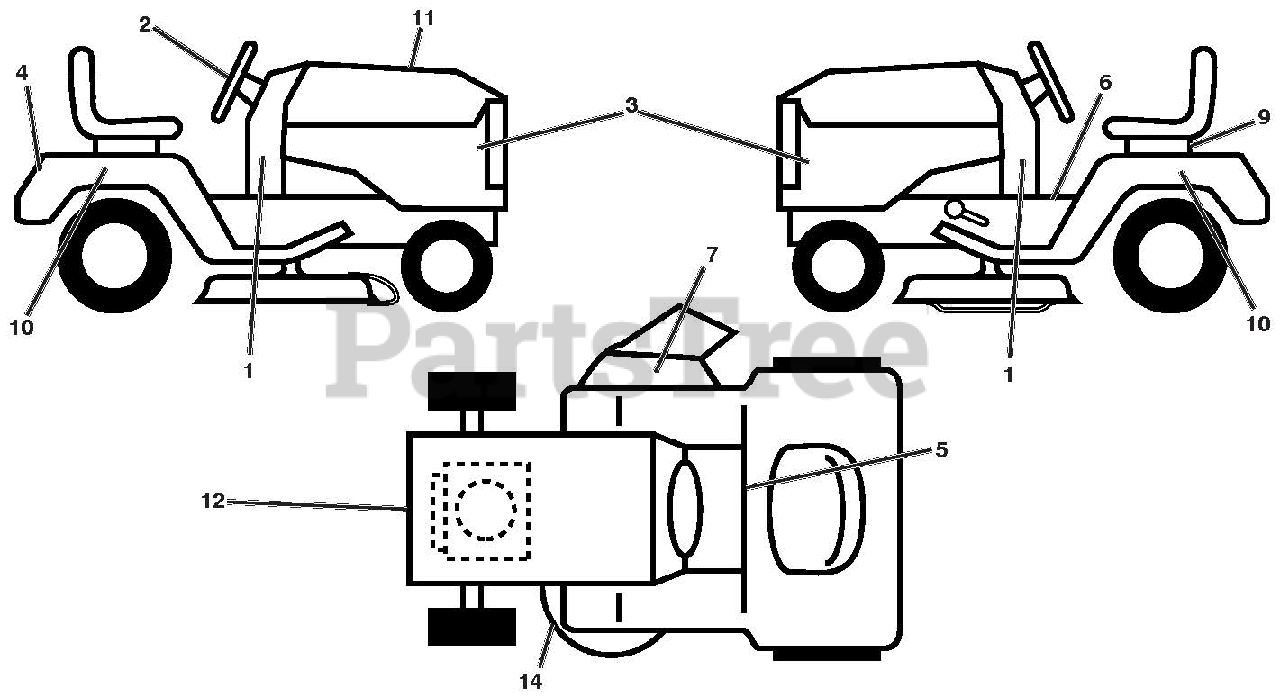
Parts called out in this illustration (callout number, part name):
1	DECAL DASH
2	DECAL.WHEEL.STEER.ARIENS
3	DECAL.SDPNL.PWRDBY B&S.ARIENS
4	DECAL.FENDER.REAR.ARIENS
5	DECAL.FENDER
6	DECAL, FENDER WARNING
7	DECAL DECK/DEFLECT. WARNING
9	DECAL.BAT.DAN/POI P/L SYM.WPN
10	DECAL, FENDER
11	DECAL REPLACEMENT
12	DECAL ENGINE
14	DECAL.V-BELT.SCH.
